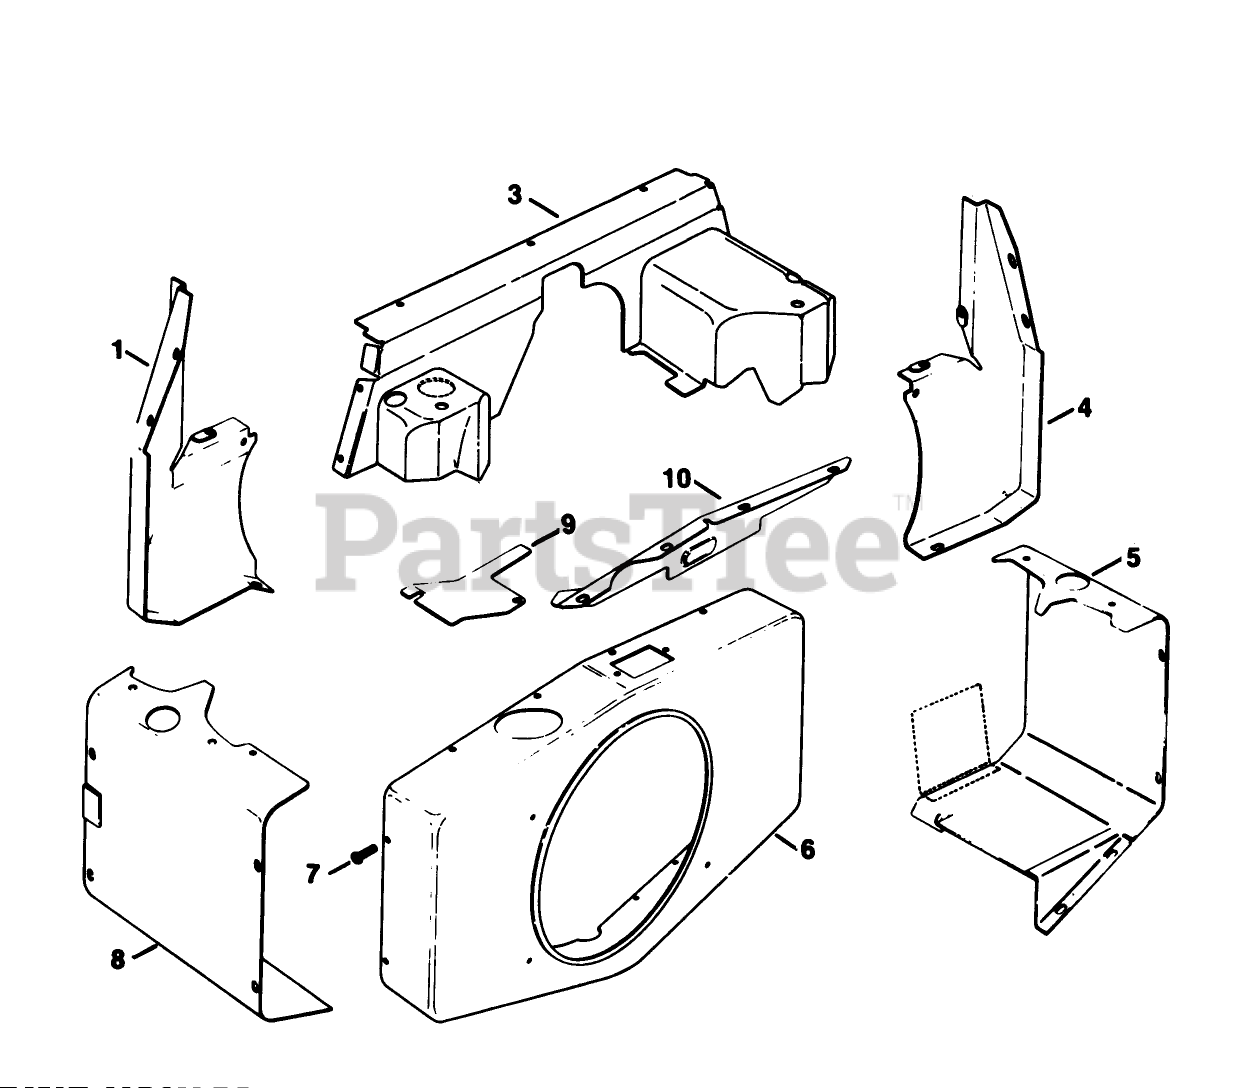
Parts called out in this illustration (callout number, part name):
1	Duct-#2 Side Air
3	Cover-Air Duct
4	#1 Side-Air Duct
5	Baffle- #1 Cylinder Head
6	Housing Blower
7	Screw
8	Baffle-#2 Cylinder Head w/Rear Cylinder Baffle
9	Baffle-Cylinder Head
10	Support-Upper Housing
